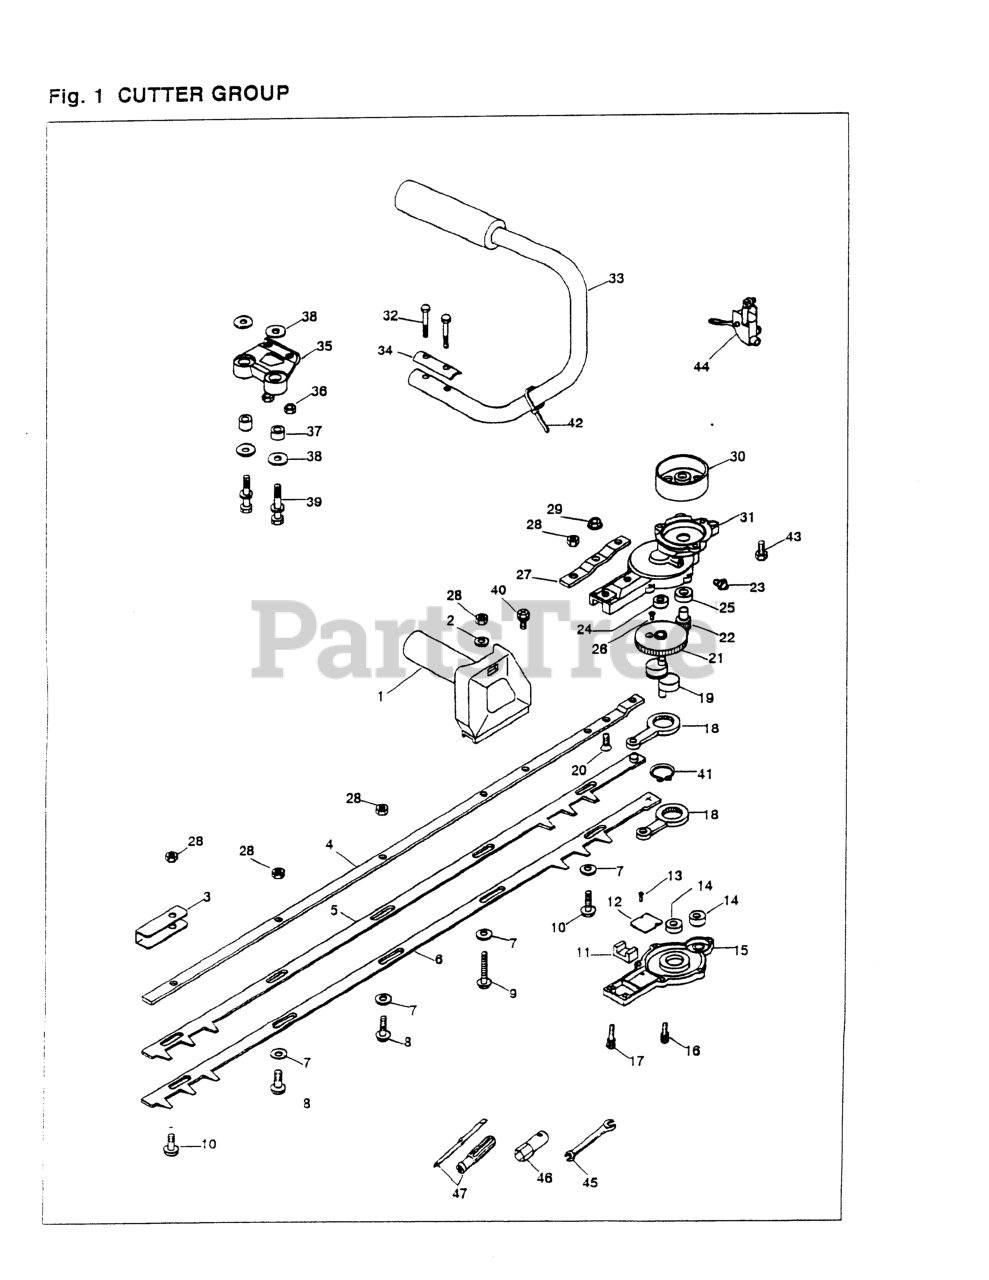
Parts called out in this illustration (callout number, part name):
1	HANDLE (RPLS -12100)
3	REINFORCE, END
5	BLADE, UPPER, 30
6	BLADE, LOWER, 30
7	WASHER (RPLS 3873-11760)
11	FELT
12	PLATE
13	SCREW, M3 x 5
14	BEARING
15	CASE, LOWER
16	BOLT, M5 x 16
17	BOLT, M5 X 20
18	ROD
19	CRANKSHAFT
20	SCREW
21	GEAR
22	PINION
23	FITTING, GREASE
24	BEARING
25	BEARING
26	SCREW
27	PLATE (RPLS 3880-11130)
28	NUT, M6
29	NUT
30	DRUM, CLUTCH
35	BRACKET
36	NUT (RPLS 3873-14470)
40	BOLT
41	RING, SNAP, M25 X 1.2
42	BAND, CABLE
43	BOLT, M6 X 14
44	LEVER ASSEMBLY
45	SPANNER, 8 X 10 (RPLS 2540- )
46	SOCKET, HEX, 3/4
47	SCREWDRIVER
NI	TOOL SET
